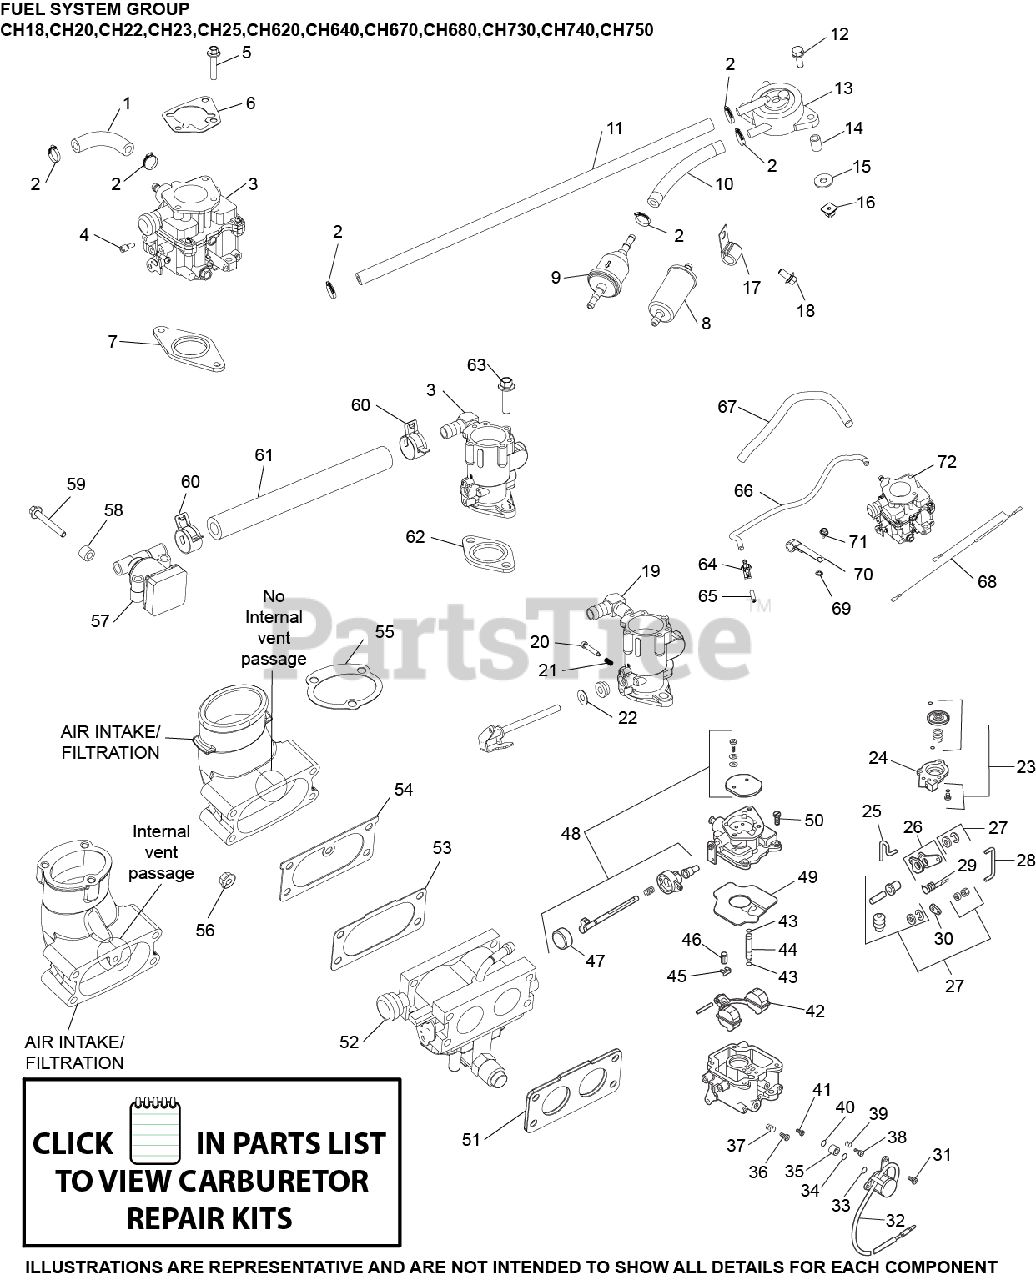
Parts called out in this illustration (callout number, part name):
1	HOSE,LW PERM.FUEL 24.00"-USE 25 111 81-S
2	CLAMP, HOSE (KM)-USE 25 237 31-S
3	KIT, CARBURETOR W/GASKETS
4	SCREW, THROTTLE STOP
5	SCREW, FLG M6X1.0X25
6	GASKET, AIR CLEANER BASE
7	GASKET, CARBURETOR
9	FILTER, FUEL
